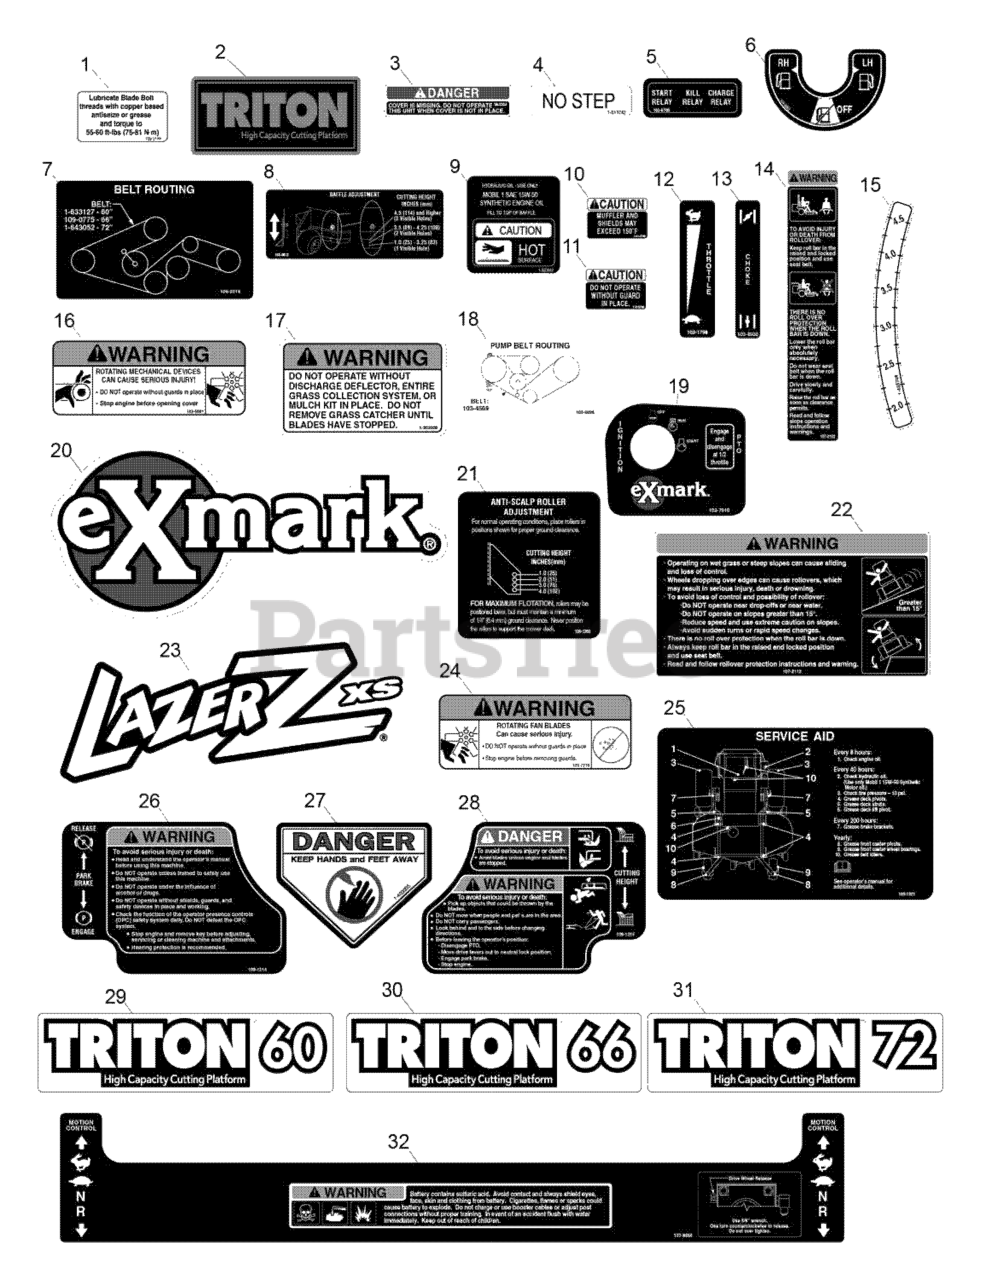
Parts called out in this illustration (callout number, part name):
1	DECAL,BOLT TORQUE
3	DECAL-COVER, MISSING
4	DECAL,NO STEP
5	DECAL,RELAY
6	DECAL-VALVE, FUEL
7	DECAL,BELT ROUTING
8	DECAL,BAFFLE ADJUSTMENT
11	DECAL-GUARD
12	DECAL,THROTTLE ONLY
13	DECAL,CHOKE
14	DECAL-WARNING, FOLDING RO
15	DECAL-HEIGHT, DECK
16	DECAL-DEVICES, ROTATING
17	DECAL-WARNING, DISCHARGE
18	DECAL,PUMP BELT ROUTING
20	DECAL,EXMARK LOGO
21	DECAL,ANTISCALP
22	DECAL-WARNING
23	DECAL,LAZER XS MODEL
24	DECAL,PUMP FAN WARNING
25	DECAL,SERVICE AID
26	DECAL,PARK BRAKE
27	DECAL-DANGER
28	DECAL,DECK HEIGHT
29	DECAL,TRITON 60
30	DECAL,TRITON 66
31	DECAL,TRITON 72
32	DECAL-CONSOLE, TOP
